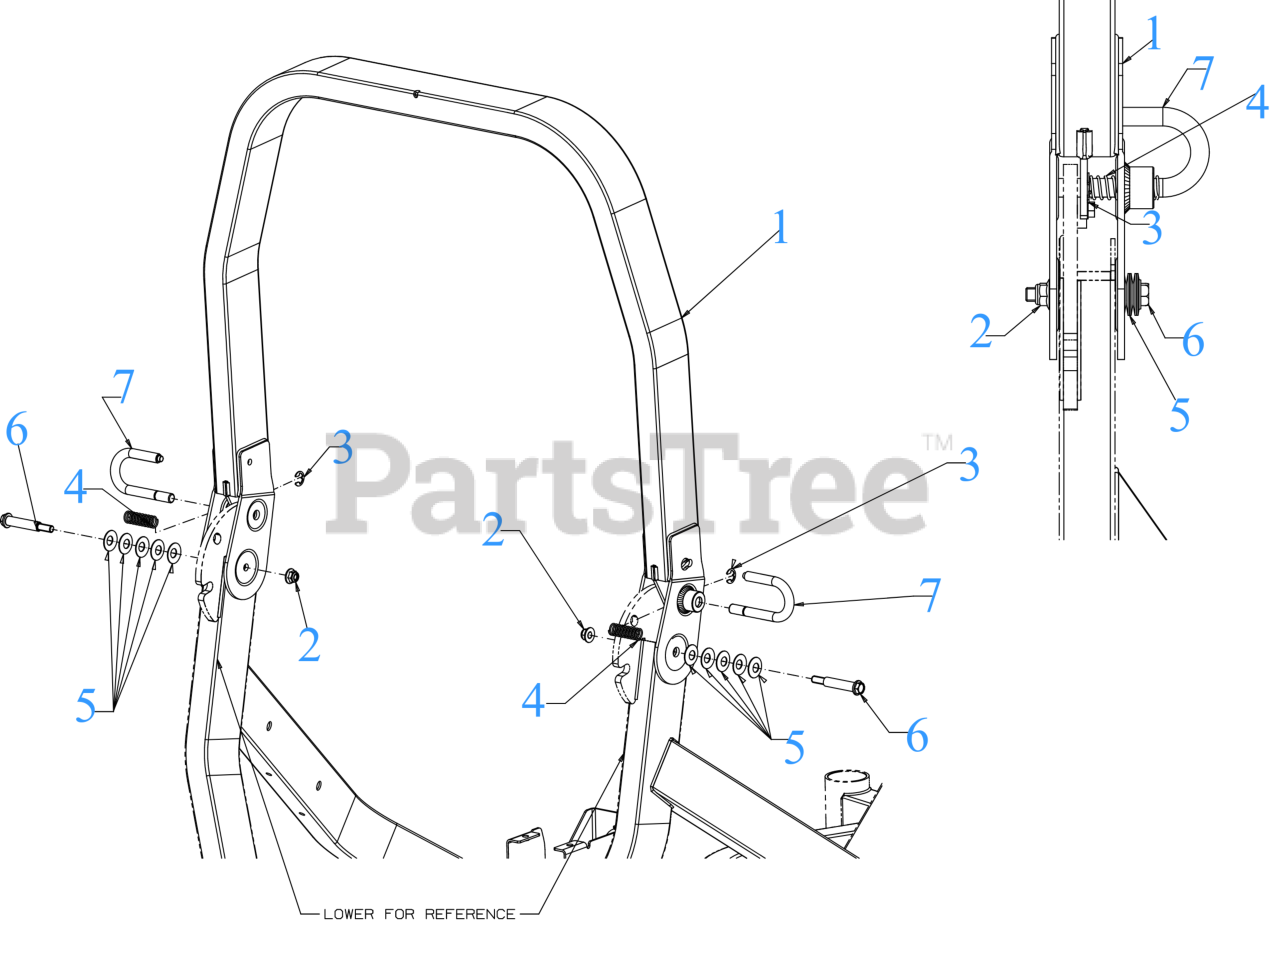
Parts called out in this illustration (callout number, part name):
1	UPPER ROPS
3	E-RING FOR .500
4	COMPRESSION SPRING
5	BELL WASHER
6	SHOULDER SCREW .50x2.12 3/8-16
7	LOCK PIN
